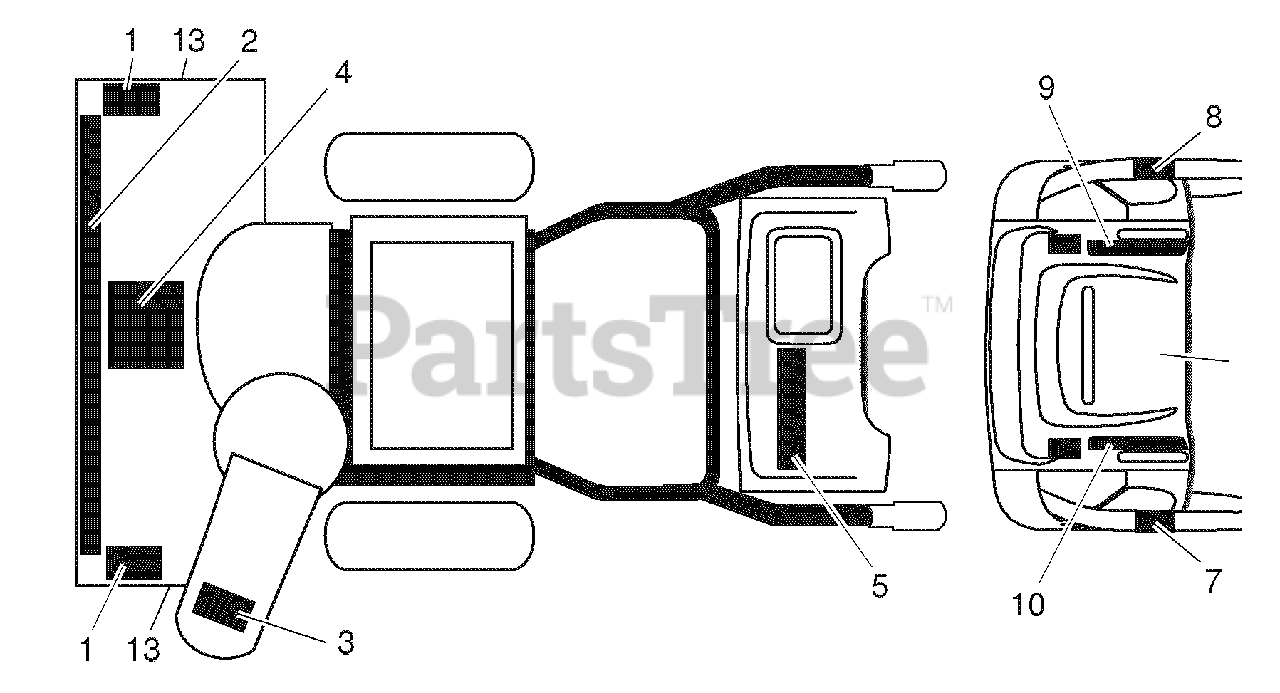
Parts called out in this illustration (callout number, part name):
1	Decal, Danger
2	Decal, Husqvarna
3	Decal, Danger, Deflector
4	Decal, Danger
5	Decal, Husqvarna, 10527SBE
6	Decal, Instruction
7	Decal, Traction Lever
8	Decal, Auger Lever
9	Decal, Speed Control
10	Decal, Remote Deflector
13	Decal, Husqvarna, Crown
